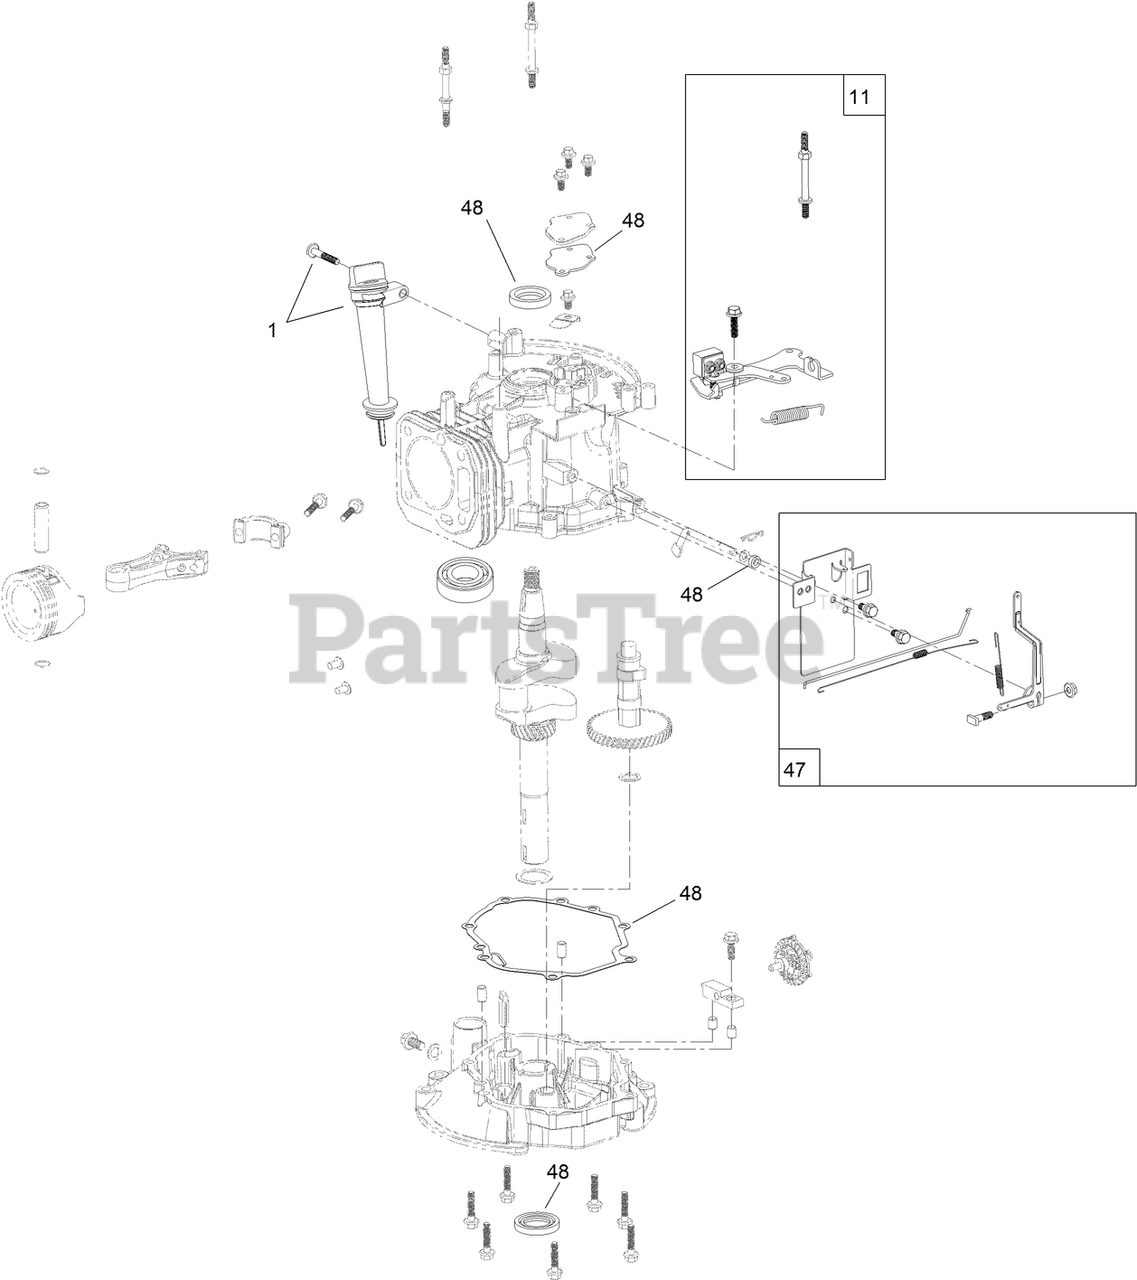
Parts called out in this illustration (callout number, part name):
1	DIPSTICK AND FILL TUBE KIT
11	BRAKE ASM RECOIL KIT
47	GOVERNOR ARM KIT
48	SEAL AND GASKET KIT
